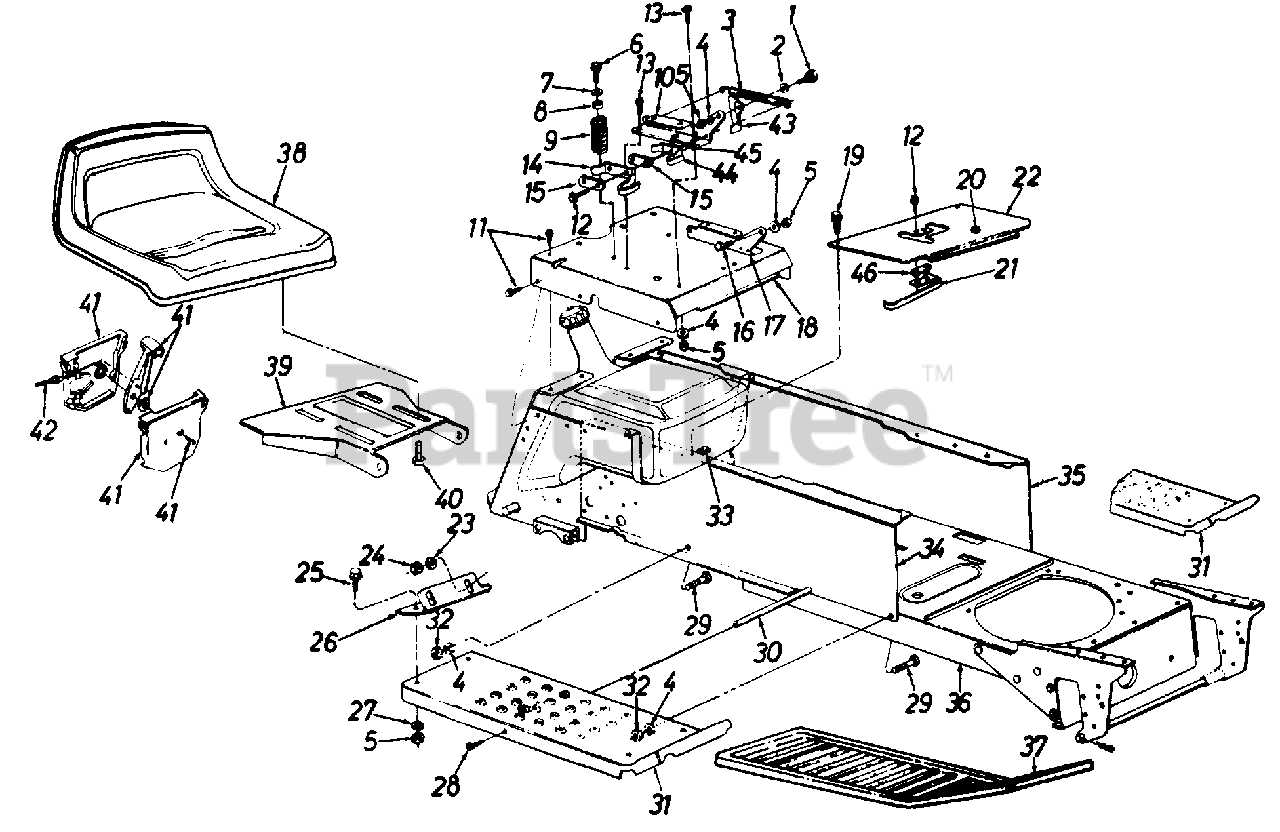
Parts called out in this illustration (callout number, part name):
1	Shld. Bolt .437" Dia. x .162"
2	Spr. Wash. .445" I.D.
3	Ext. Spring 5.31" Lg.
4	L-Wash. 5/16" I.D.
5	Hex Nut 5/16-18 Thd.
6	Hex Wash. Hd. Tap Scr. 5/16-18 x .7" Lg.
7	Fl-Wash. .344" I.D.
8	Bushing
9	Compression Spring
12	Hex Wash. Hd. AB-Tap Scr. #8 x .5" Lg.
13	Torx Hd. AB-Tap Scr. 5/16-18 x .75" Lg.
14	Spring Switch
15	Insulator Plate
16	Shld. Bolt .437" Dia. x .162"
20	Snap Bushing
21	Reverse Safety Switch
23	L-Wash. 1/4" I.D.
24	Hex Nut 1/4-20
25	Hex Bolt 5/16-18 x .75" Lg.
28	Truss Mach. Scr. 5/16-18 x .75" Lg.
29	Rib Neck Bolt 5/16-24 x .75" Lg.
30	Running Board Rod
33	Speed Nut #10 Z
34	R.H. Side Frame
35	L.H. Side Frame
38	Seat 8-7/8" High
40	Hex Tap Scr. 3/8-16 x .75" Lg.
41	Throttle Control Box Ass'y.
42	Throttle Control Wire 35" Lg.
43	Seat Lift Bracket
44	Seat Spring Switch
45	Insulator Boss Plate
46	Insulator Not Plate
